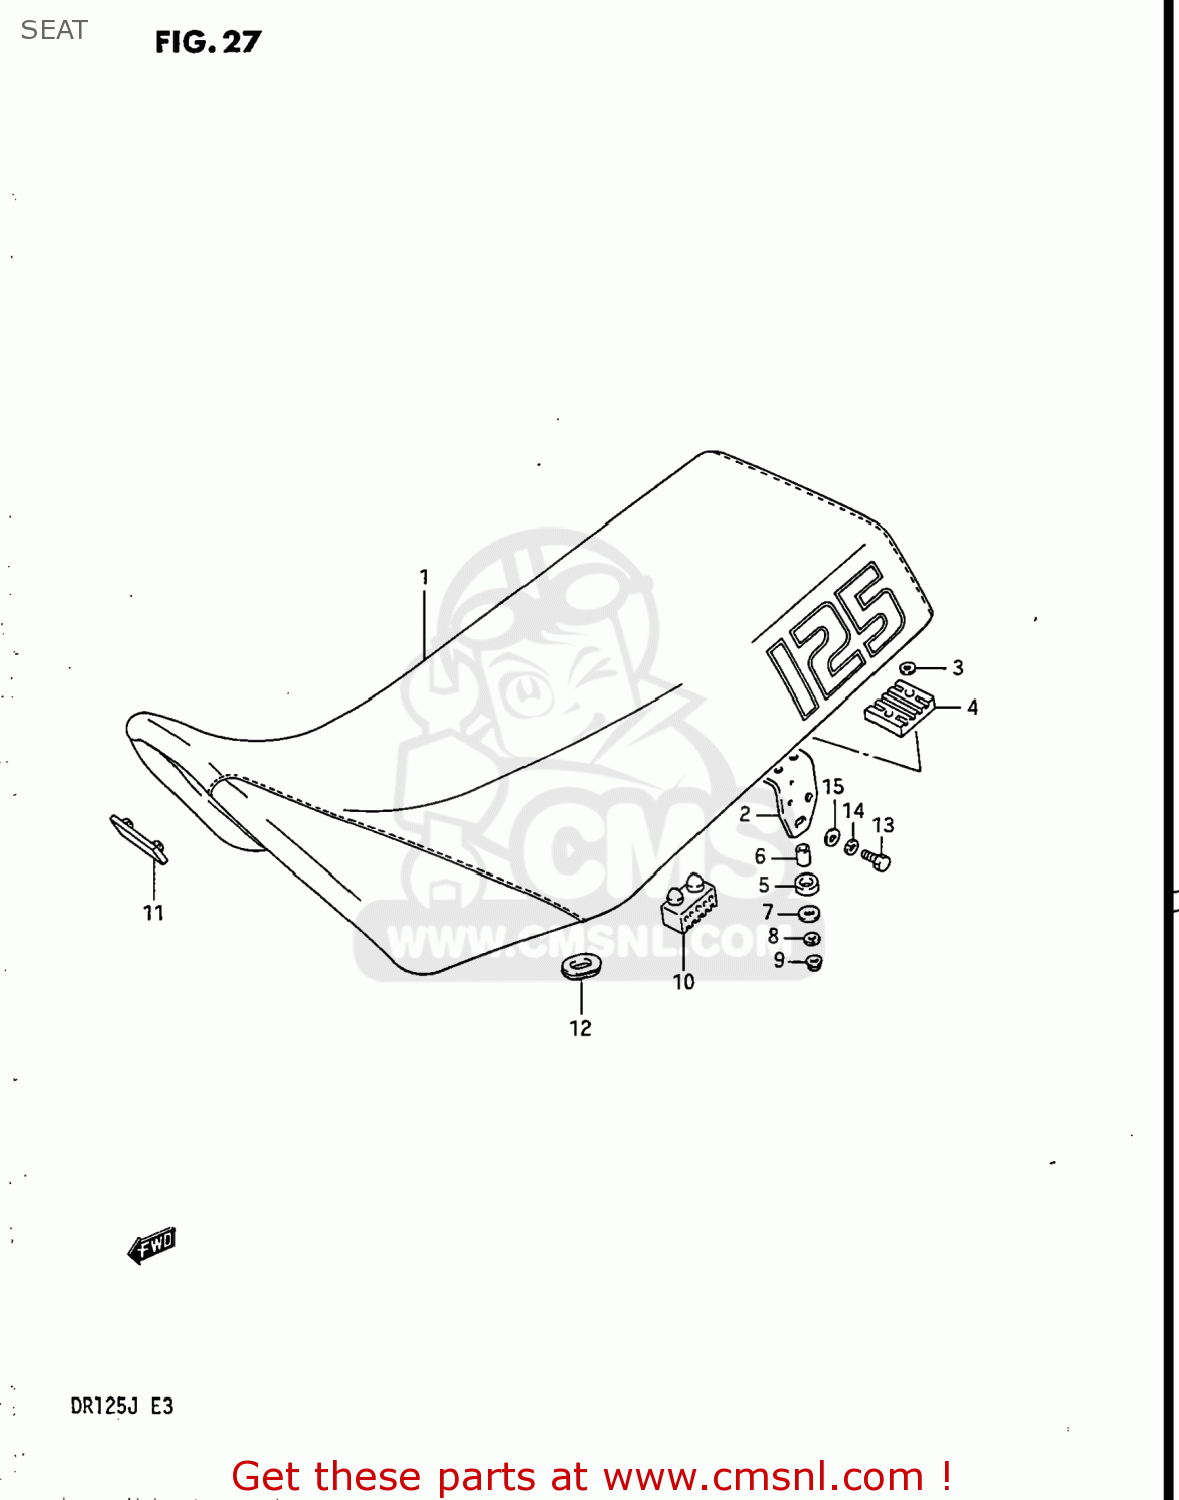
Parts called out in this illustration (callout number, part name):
1	SEAT ASSEMBLY
2	BRACKET,LEFT
3	WASHER, LOWER
4	CUSHION,FR PLATE
5	CUSHION,SEAT FR
6	SPACER,SEAT SUPPORT
7	WASHER
8	WASHER,LOCK
9	NUT 6MM
10	CUSHION,SEAT(40X20X15)
11	CUSHION
12	CUSHION
13	BOLT
14	WASHER,LOCK,8.
15	WASHER
